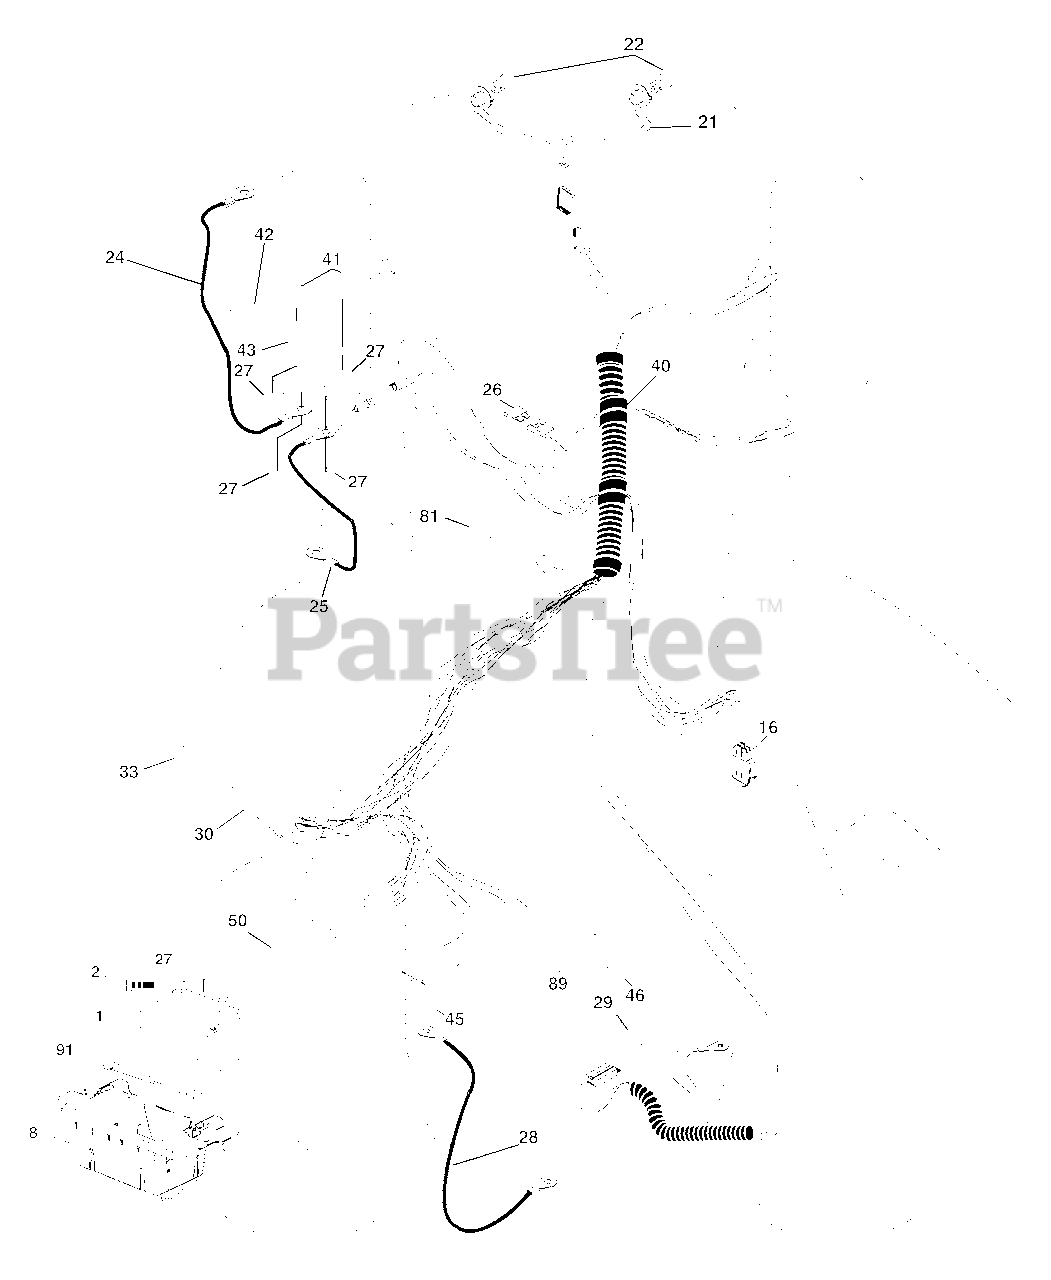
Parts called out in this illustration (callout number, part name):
1	Battery
2	Bolt Hex Hd 1/4-20 unc x 3/4
8	Box Battery
16	Switch Interlock Push-In
21	Harness Asm Light W/4152j
22	Bulb Light #1156
24	Cable Battery 6 Ga. 11" red
25	Cable Battery 6 Ga. 22" red w/16 wire
26	Fuse 20 AMP
27	Nut Keps Hex 1/4-20 unc
28	Cable Ground black
29	Switch Plunger Normal Op Olive
30	Switch Ign
33	Key Ign Molded Generic
40	Harness Ign.
41	Bolt Blk Fin Hex 1/4 - 20 x 1/2
42	Cover Terminal Red
43	Solenoid
46	Hourmeter Snap-In
50	Switch PTO
81	Relay Asm.
89	Bracket Snap-In Hourmeter
90	Cover Terminal
91	Strap Battery
